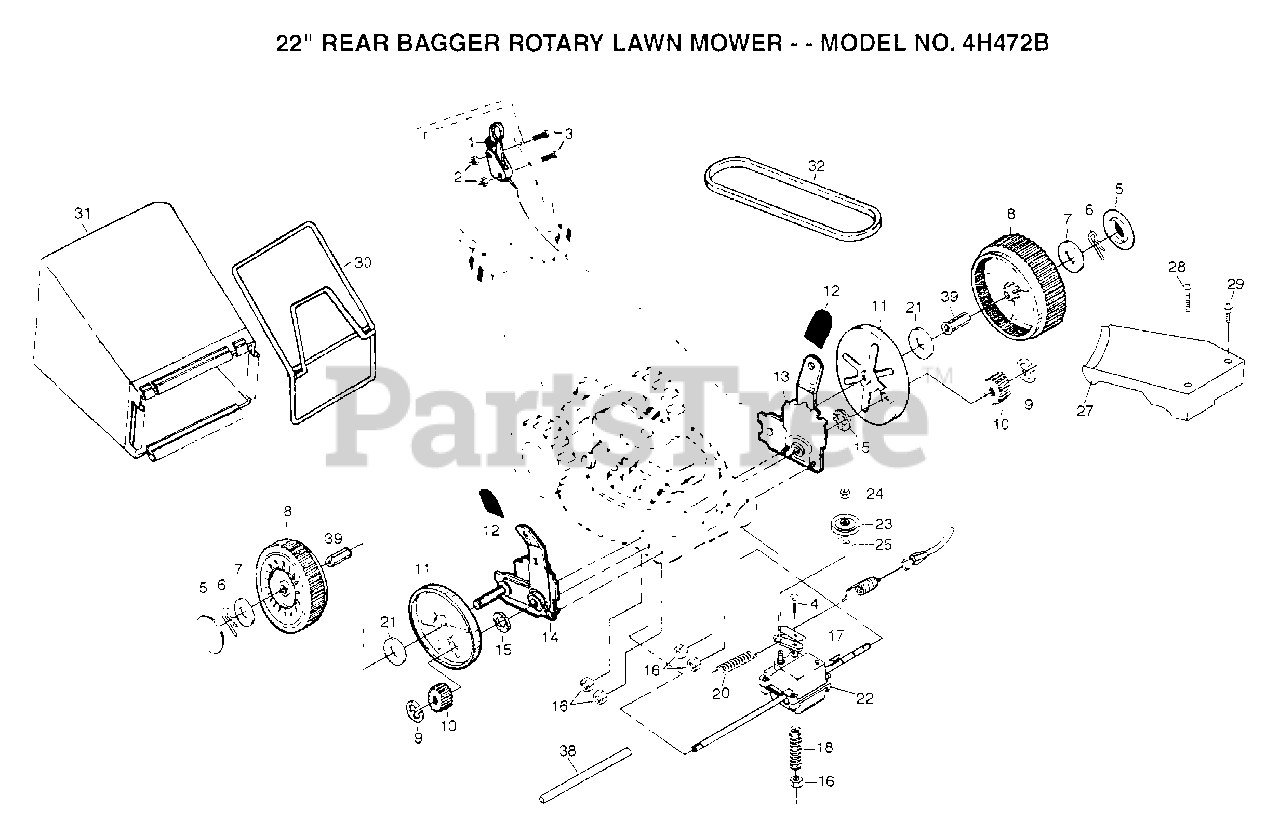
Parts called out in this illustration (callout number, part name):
1	CONTROL.DRIVE
2	LOCKNUT
3	SCREW
4	BOLT.1/4-20X2.0
5	HUB CAP
6	RETAINER CLIP PM
7	WASHER
8	WHEEL.8X2.LP.PR
9	E-RING.7/16.RE.
10	PINION.GEAR
11	DUST SHROUD PM
12	KNOB PM
15	WASHER PM
17	HI PRO KEY
18	SPRING.TENSION
20	SPRING
21	WASHER FLUT
23	PULLEY.DRIVEN
24	LOCKNUT
25	BEARING
27	"COVER.DRIVE 22""RD"
30	CATCHER FRAME
31	GRASS BAG
38	DRV SHAFT TUBE PM
39	BUSHING.HEX
